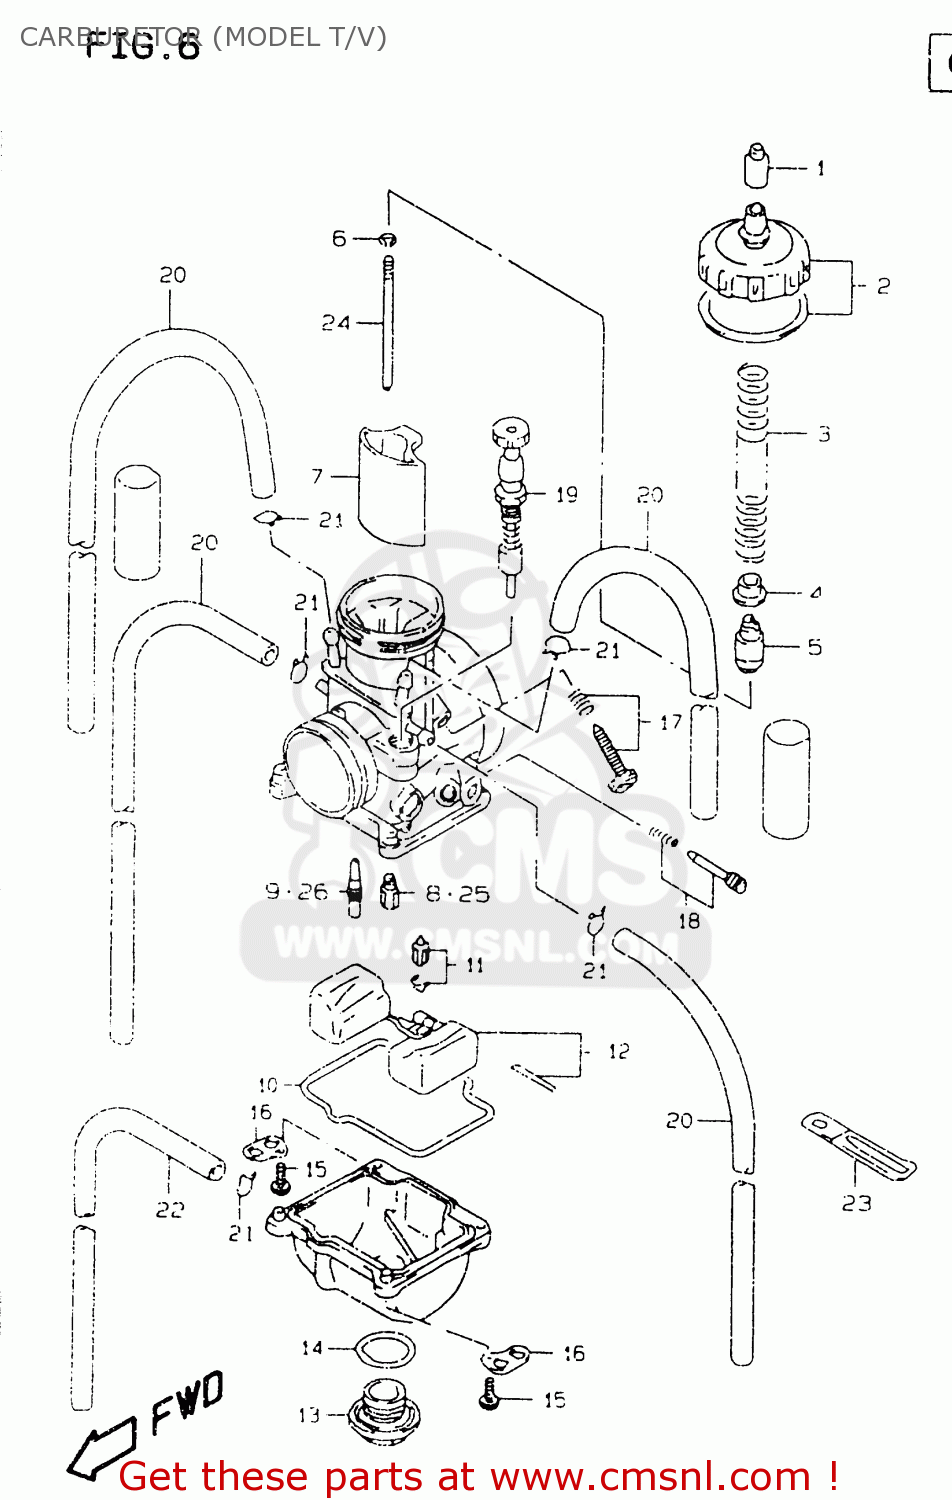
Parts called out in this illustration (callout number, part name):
1	CAP,CARBURETOR
2	CAP SET,TOP
3	SPRING,THROTTLE VALVE
4	COLLAR,THROTTLE VALVE
5	HOLDER,CABLE
6	CLIP,NEEDLE
7	VALVE,THROTTLE
8	JET,MAIN(170)
9	JET,SLOW(50)
10	GASKET,FLOAT CHAMBER
11	VALVE SET,FLOAT
12	FLOAT SET
13	BOLT,DRAIN
14	O RING
15	SCREW
16	PLATE
17	SCREW SET,STOP
18	SCREW SET,AIR
19	STARTER VALVE
20	HOSE(4X7X620)
21	CLIP
22	HOSE(3.5X6.5X600)
23	CLAMP(L:45)
24	NEEDLE(R1469MS)
25	JET,MAIN(145)
26	JET,SLOW(35)
